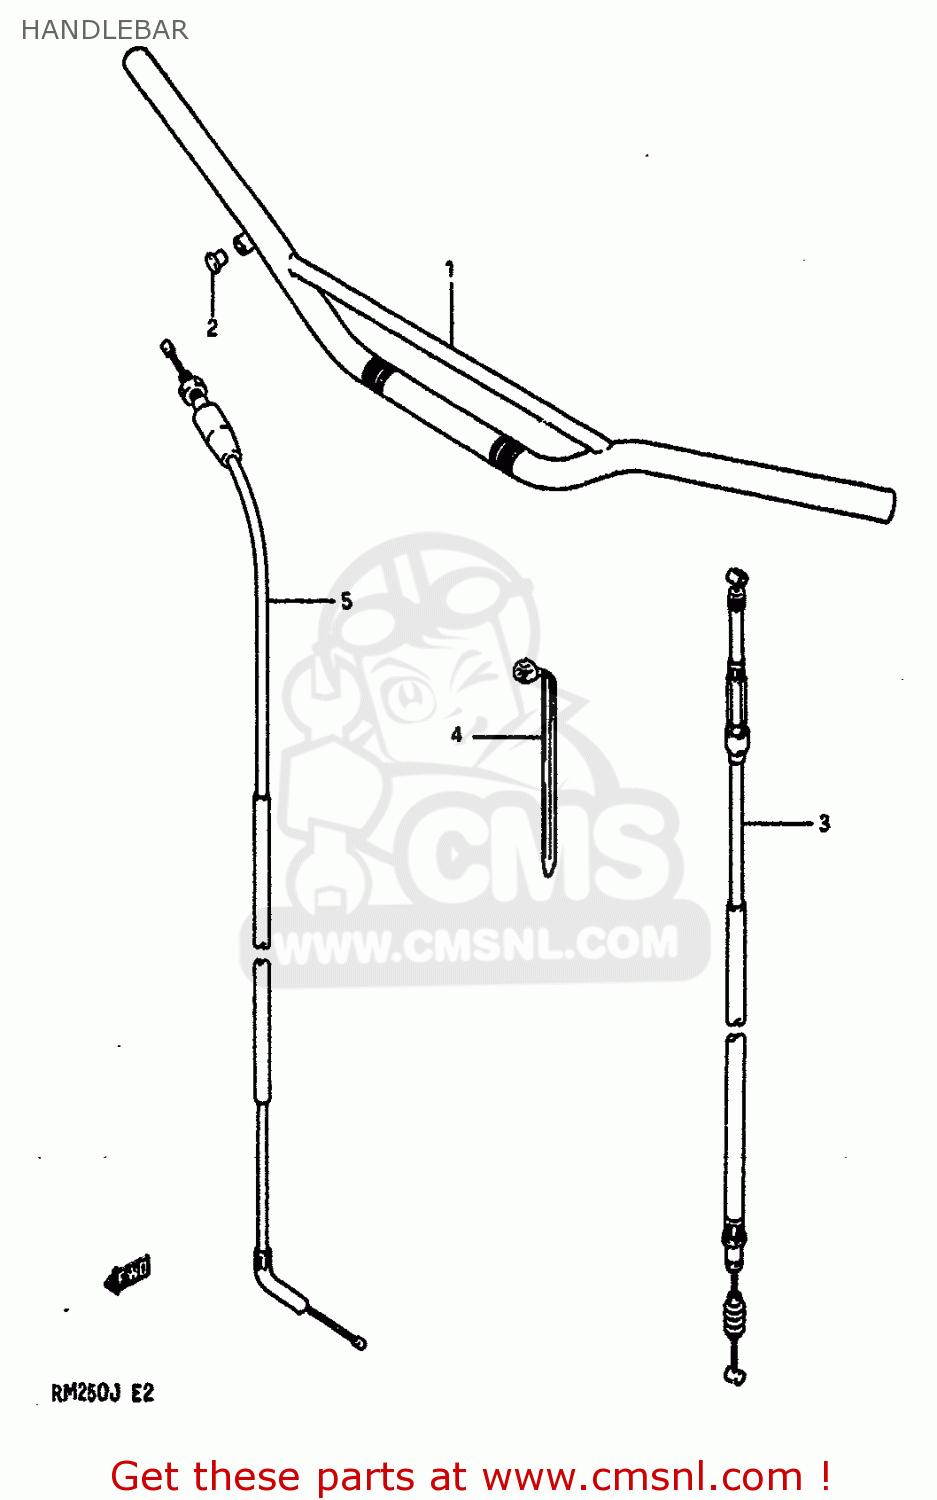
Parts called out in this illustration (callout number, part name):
1	HANDLEBAR
2	CAP(OD:14)
3	CABLE ASSEMBLY,CLUTCH
4	CLAMP(L:165)
5	CABLE ASSEMBLY,THROTTLE
